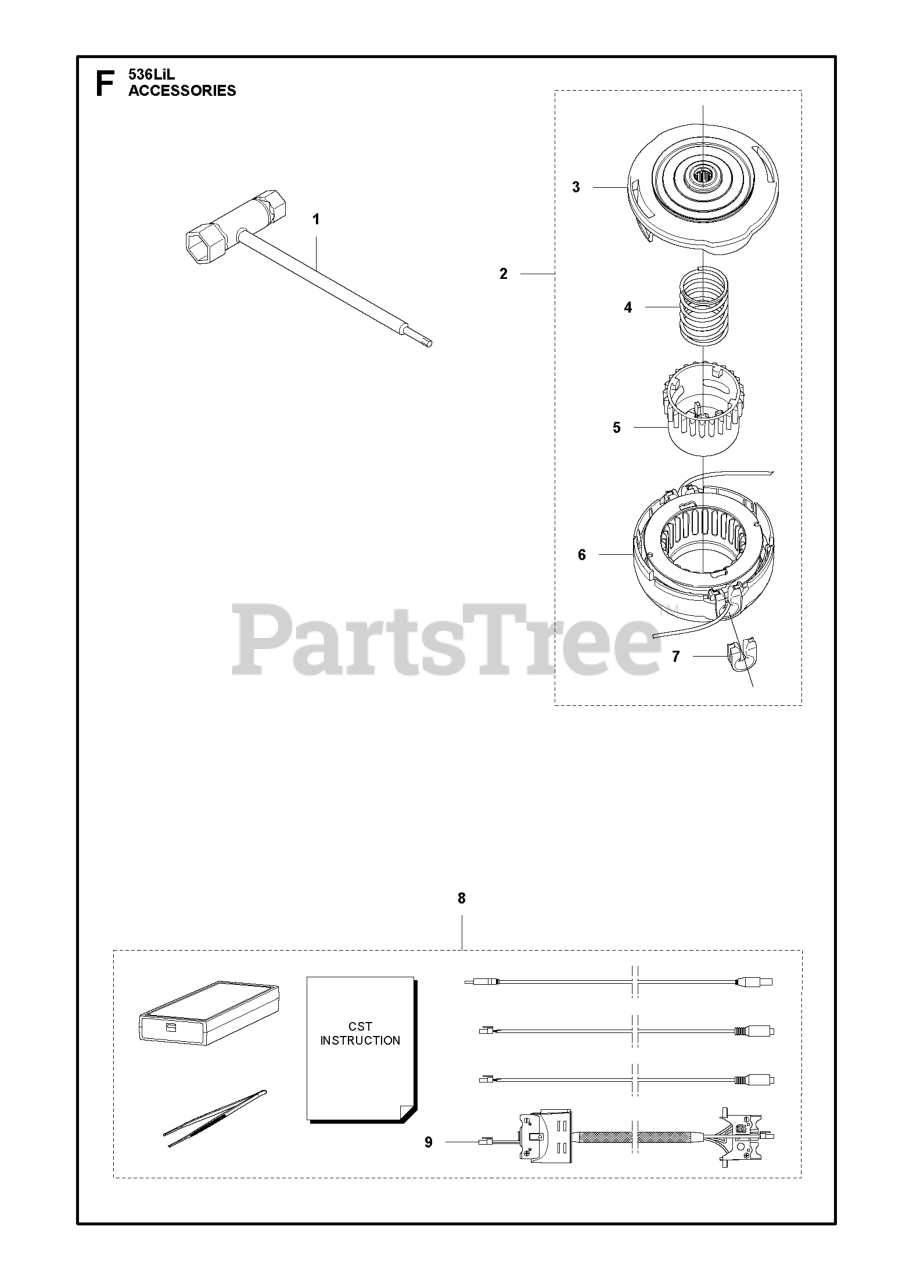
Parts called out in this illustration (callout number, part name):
1	COMB.TOOL 8-10-14
2	RP_T25 TRIMMER HEAD 10MM(BATT
3	HOUSING ASSY
8	DIAGNOSTIC TOOL KIT
9	WIRING ASSY
